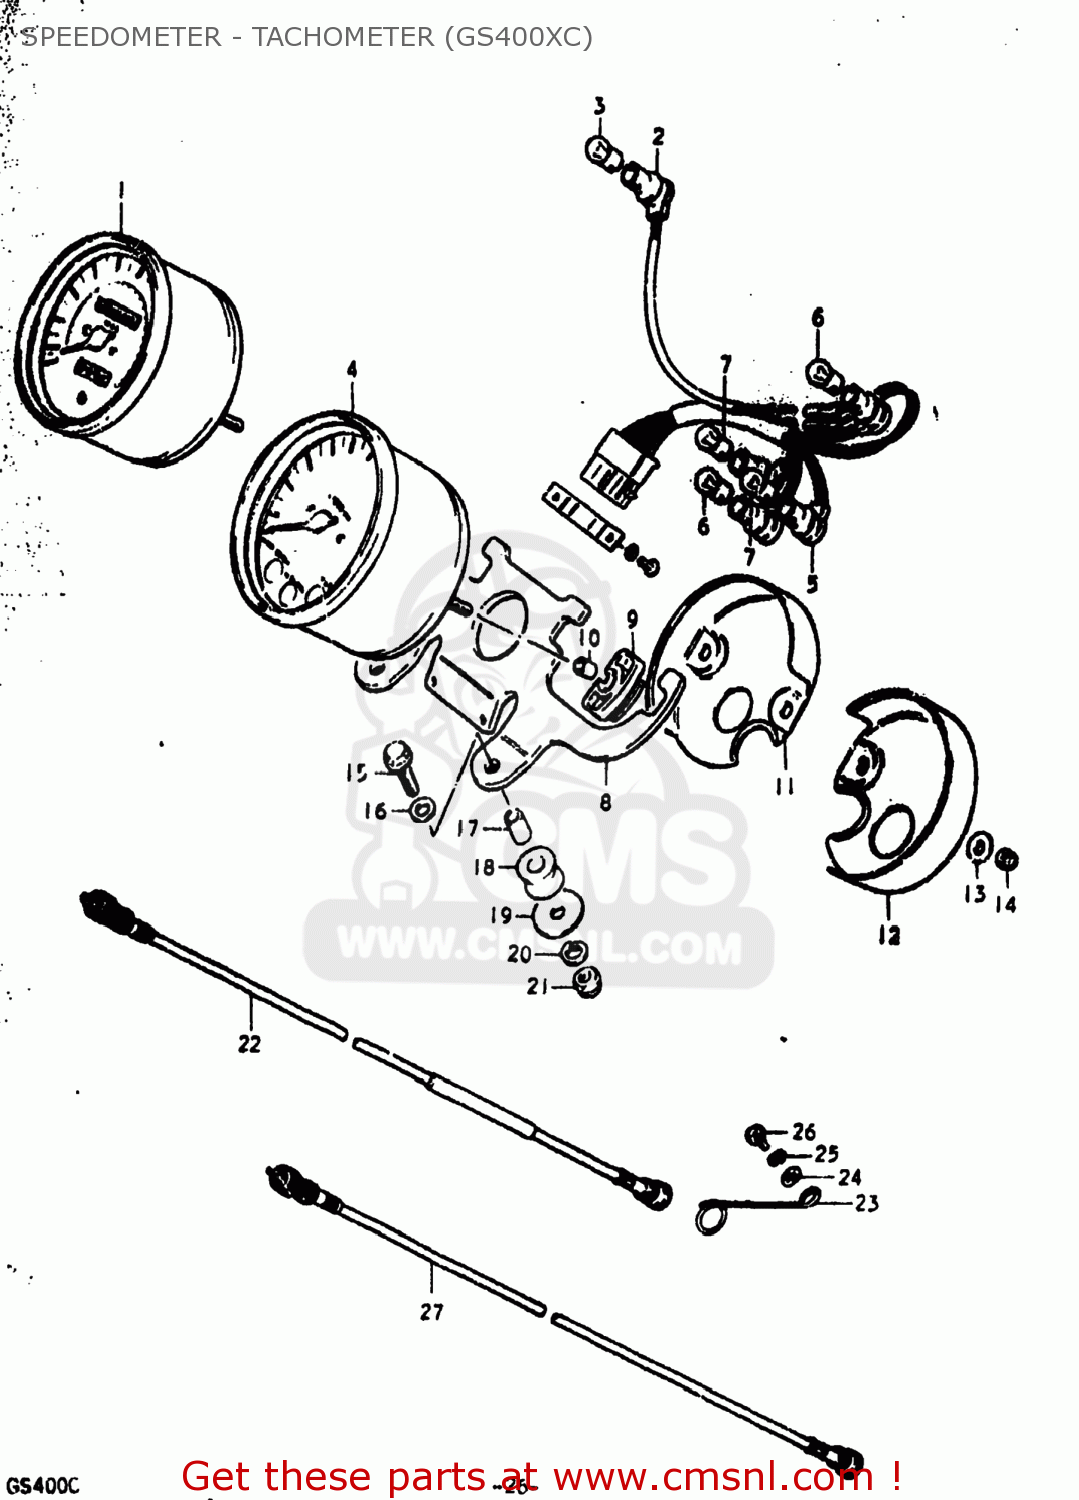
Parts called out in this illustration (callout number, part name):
1	SPEEDOMETER ASSEMBLY
2	SOCKET,METER
3	BULB(12V3.4W,STANLEY,A72A)
4	METER,TACHOMETER
5	SOCKET,TACHOMETER
6	BULB(12V3.4W,STANLEY,A72A)
7	BULB(12V1.7W,A71A)
8	BRACKET,METER
9	CUSHION,METER
10	SPACER,METER
11	PANEL,METER
12	COVER,METER,UNDER
13	WASHER,METER
14	NUT
15	BOLT
16	WASHER
17	SPACER (6.1X8X15.5)
18	CUSHION
19	WASHER
20	LOCK WASHER
21	NUT
22	CABLE ASSEMBLY,SPEEDOMETER
23	GUIDE,SPEEDOMETER CABLE
24	WASHER 6MM
25	LOCK WASHER
26	BOLT, UPPER
27	CABLE ASSEMBLY,TACHOMETER
